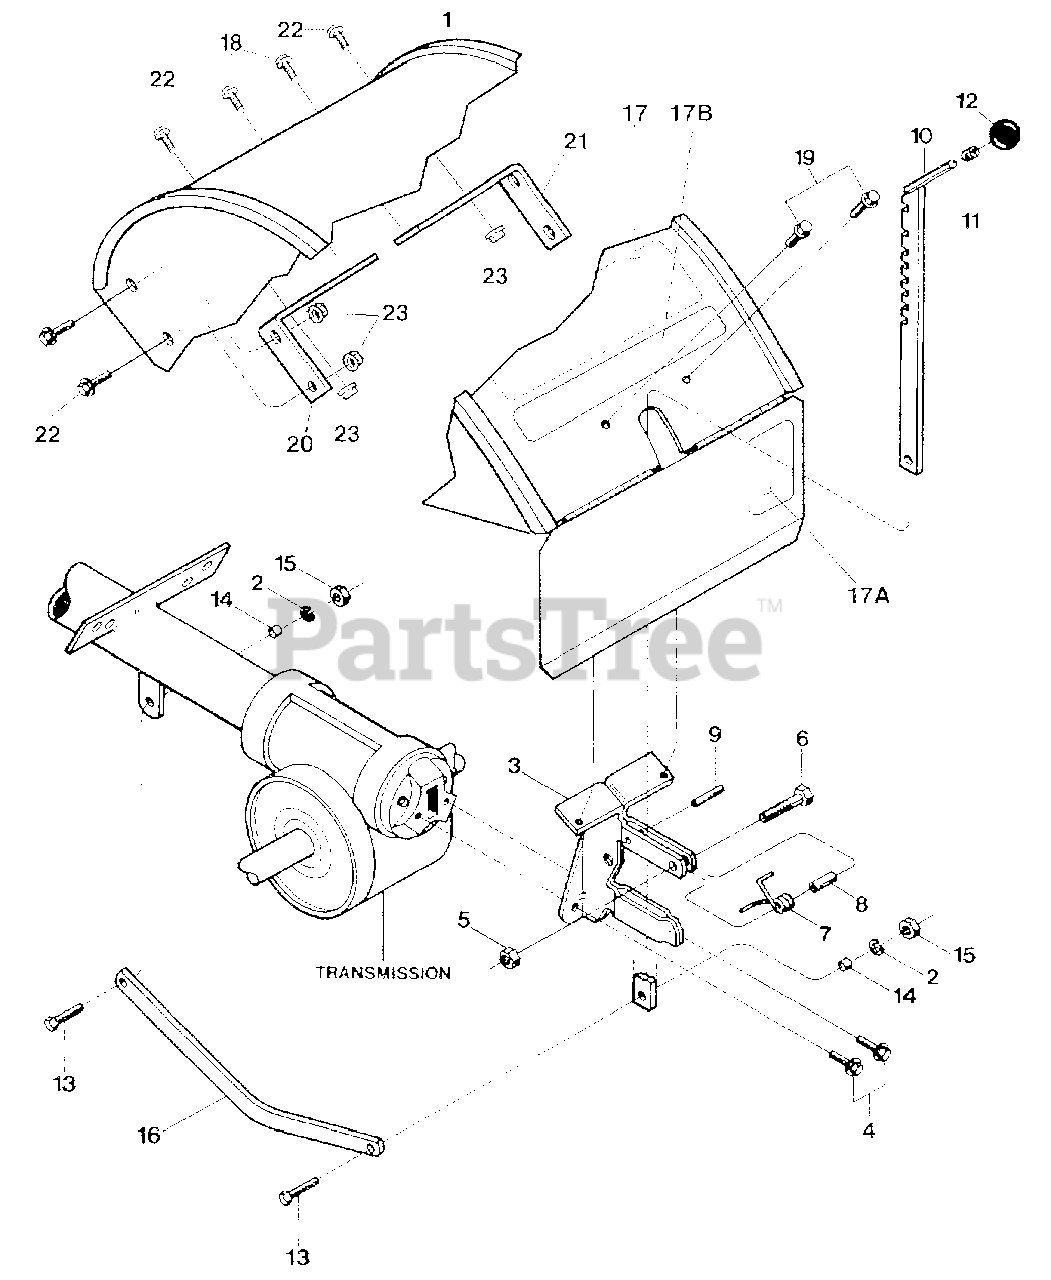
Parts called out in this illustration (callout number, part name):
1	Hood-tine cover, with hinged flap
2	Lockwasher-3/8
3	Bracket-hood & depth regulator
4	Screw-flanged hex hd, 5/16-18 x 5/8
5	Locknut-hex, 1/4-20
6	Screw-hex hd , 1/4-20 x 1
7	Spring-depth regulator plunger
8	Spacer
9	Roll Pin-1/4 x 1 (spiral)
10	Bar Assembly-depth adjustment
11	Ring-retaining, tolerance ring
12	Knob-depth regulator
13	Screw-hex hd, 3/8-16 x 1-1/4
14	Bushing-spacer, drag bar
15	Nut-hex, 3/8-16
16	Drag Bar-depth regulator
17	Decal-tiller operating instructions
17A	Decal- Warning
17B	Decal- Logo
18	Screw-hex hd, self-tapping, 5/16-18 x 1/2
19	Screw-flanged hex hd, self-tapping, 1/4-20 x 1/2
20	Bracket- support, left
21	Bracket- support, right
22	Bolt- hex hd , 5/16"-18 x 5/8"
23	Nut- hex, 5/16"-18
